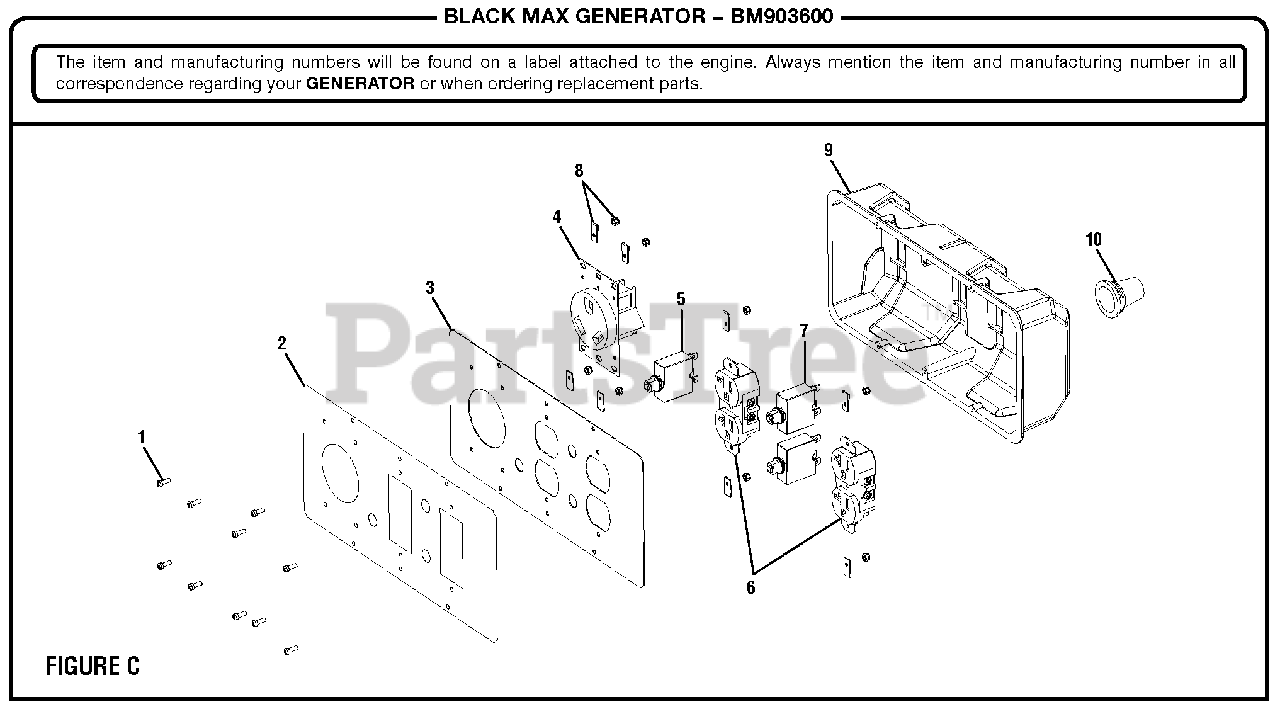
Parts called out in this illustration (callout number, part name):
1	Screw (#6-20 x .38 in., Type B)
2	Electrical Panel Label
3	Electrical Panel Faceplate
4	Recepticle 120V 30A Rv
5	Circuit Breaker 30 Amp 1 Pole
6	120 Volt Duplex Receptacle
7	Circuit Breaker 20 Amp 1 Pole
8	Nut, Hex #6-32 Nyloc
8	U- Clip Nut #6
9	Control Box Housing
10	Wiring Rubber Boot
